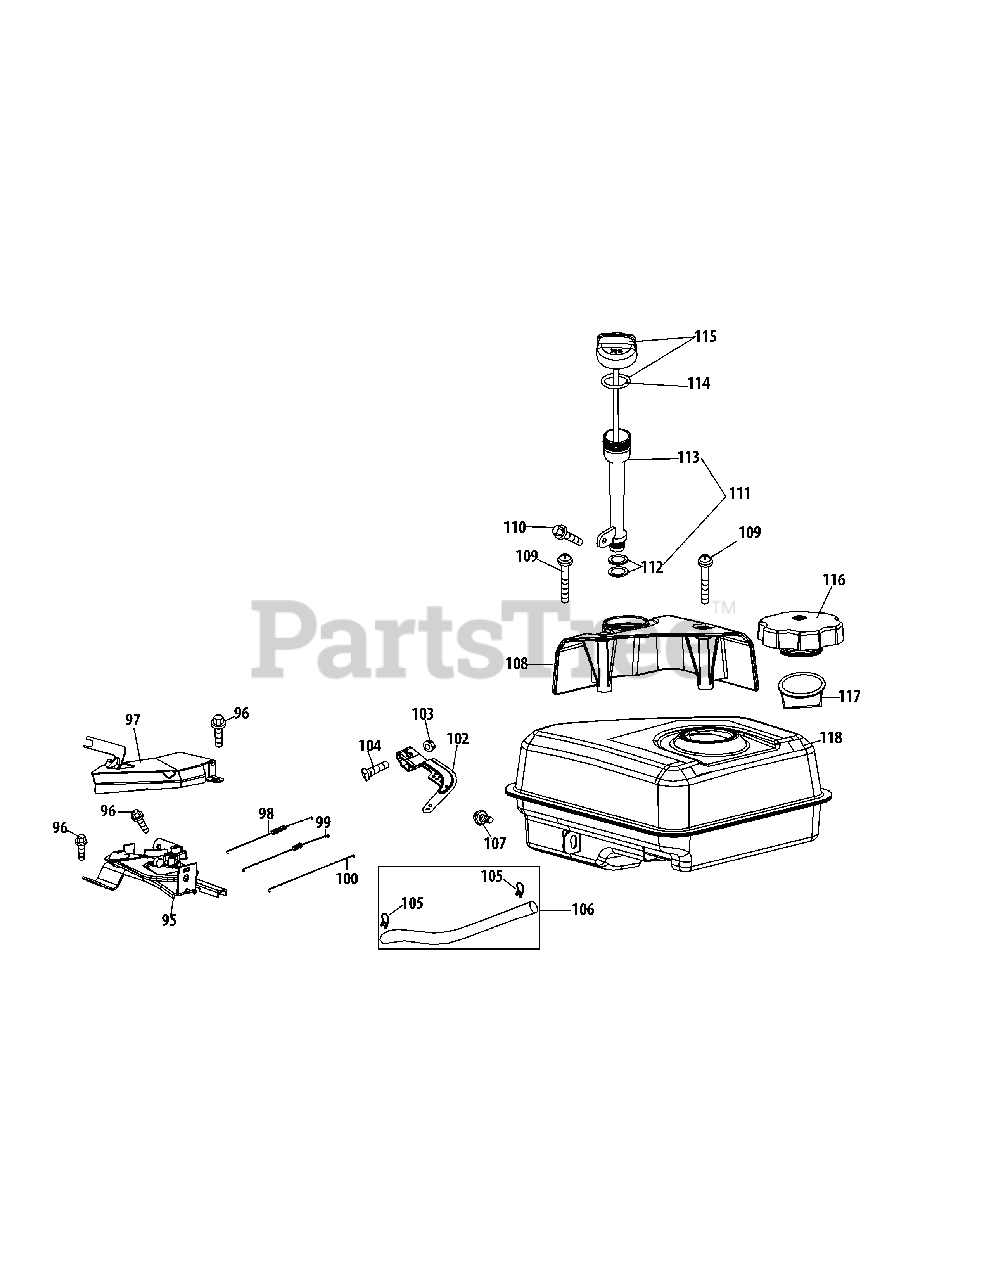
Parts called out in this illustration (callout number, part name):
95	Throttle Bracket
96	Bolt M6×12
97	Governor Linkage Shield
98	Governor Spring
99	Throttle Linkage Spring
100	Throttle Linkage
102	Governor Arm
103	Nut M6
104	Governor Arm Bolt
105	Fuel Hose Clamp
106	Kit-Fuel Line
107	Bolt M6×12
108	Dipstick Decoration Cover
110	Bolt M6×12
111	Oil Fill Tube Assembly
112	Dipstick O-Ring
113	Oil Fill Tube
114	Dipstick O-Ring
115	Dipstick Asm
116	Fuel Cap Assembly
117	Fuel Level Indicator
118	Fuel Tank Assembly
